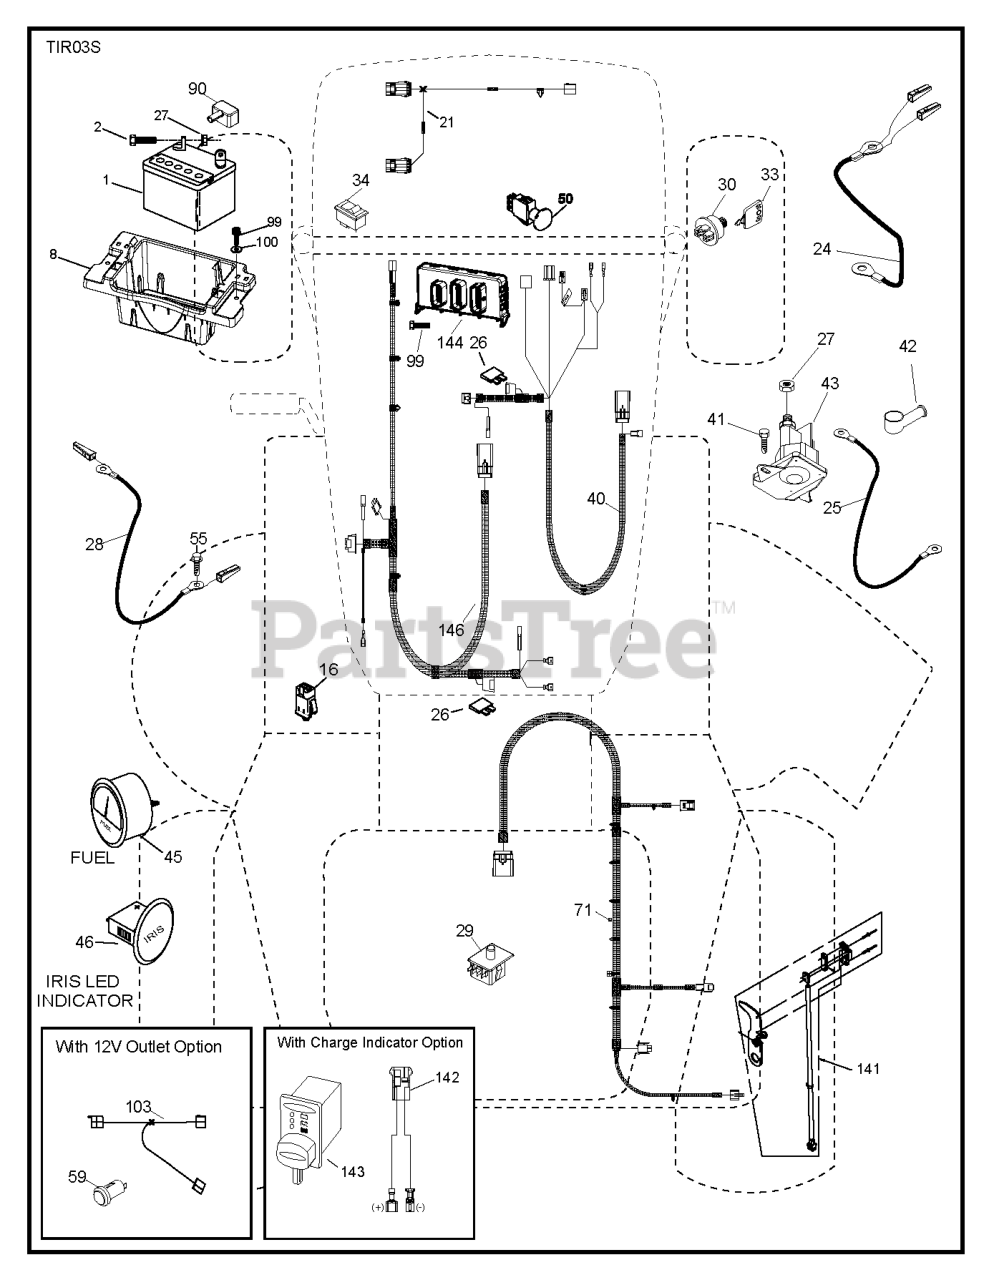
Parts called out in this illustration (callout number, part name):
1	Battery 12 Volt 25 Amp
2	BOLT.HEX.1/4.X.3/4.DICHROMATE
8	TRAY.ASM.BATTERY.FRT.TEX.CARB
16	SWITCH INTERLOOK PUSH-IN
21	HARNESS LIGHT ASSY TRACTOR,
24	PRIMARY CABLE POSITIVE, TWO HA
25	CABLE.STARTER.8GA.17.5
26	FUSE 20AMP
27	NUT
28	GROUND CABLE TWO HARNESS TAPS,
29	SWITCH SEAT, 4 PIN NC/NO
30	SWITCH.IGN.DELTA.W.LGH.ROS
33	KEY.CHAIN.BLISTER.PACK.GEN.USA
40	WIRING ASSY DASH, IRIS, 300, T
41	SCREW
42	TERMINAL COVER
43	SOLENOID.STARTER.BRASS.PLUNGER
45	GAUGE.FUEL.LEVEL. ROUND.2"
46	GAUGE.INDCTR.RND.2"FARIA.6ICNS
50	SWITCH.PTO.8TERMINAL.STD.BLK
55	SCREW 5/16"
71	WIRING ASSY CHASSIS, IRIS, 300
90	COVER.TERMINAL.BATTERY
99	SCREW HEXWSHR 1/4-20X3/4
100	WASHER
141	KIT.G700/G730.ROS 71750
144	CONTROL.UNIT.RIDE.ON.IRIS.BASE
146	WIRING ASSY ENGINE, IRIS, 300,
